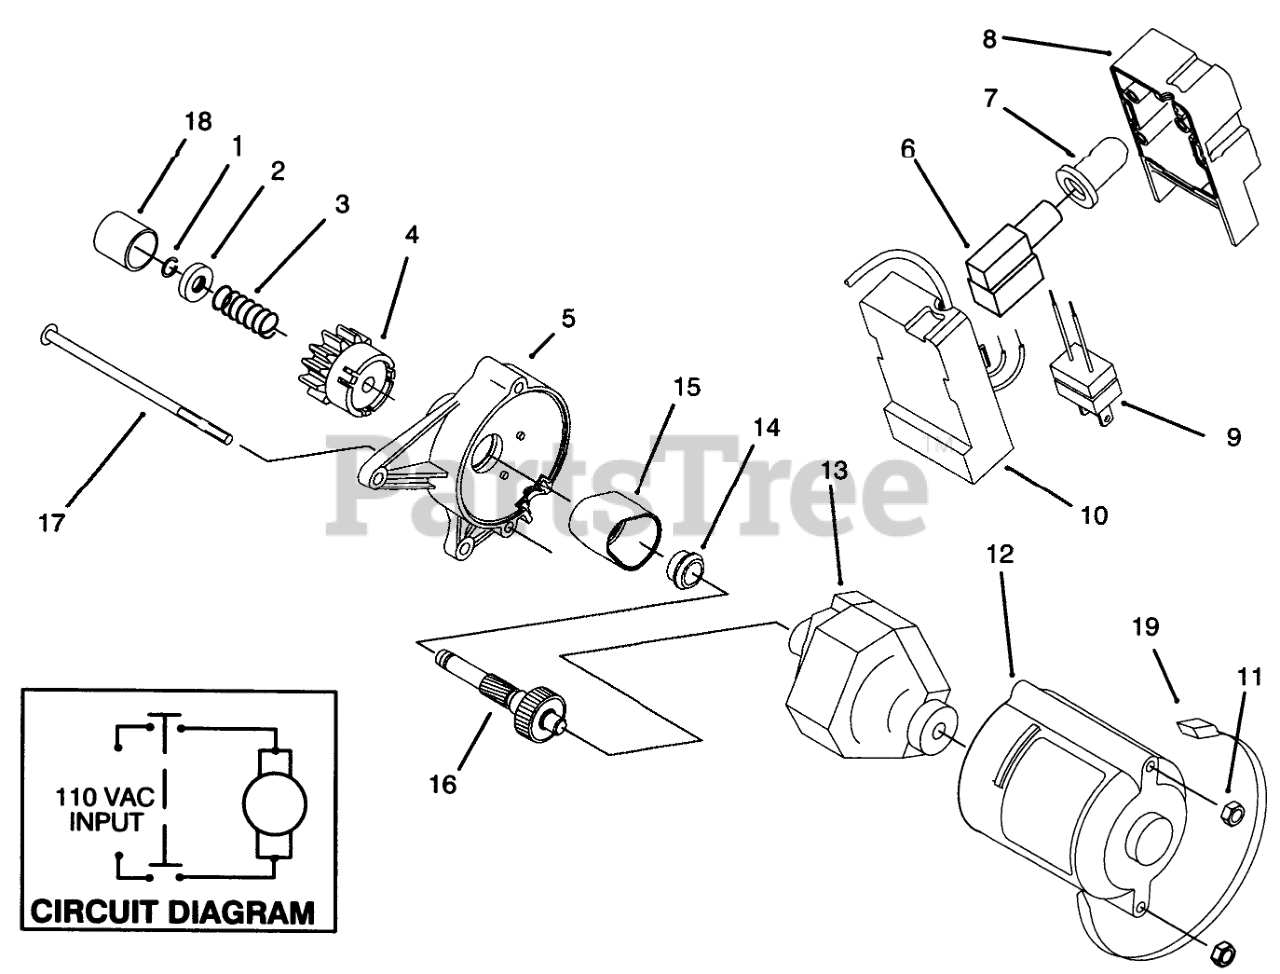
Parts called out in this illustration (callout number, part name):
1	RING-LOCK
2	PINION STOP
3	SPRING
4	PINION ASM
5	Housing-Starter
6	SWITCH-STARTER
7	BOOT-SWITCH
8	Cap-Switch Housing
9	Plug
10	OBS BASE X
11	NUT-LOCK, NI
12	HOUSING COVER
13	STARTER MOTOR ASM
14	BUSHING
15	COVER-GEAR
16	Asm-shaft & Gear
18	CAP-PINION
19	TIE-CABLE
